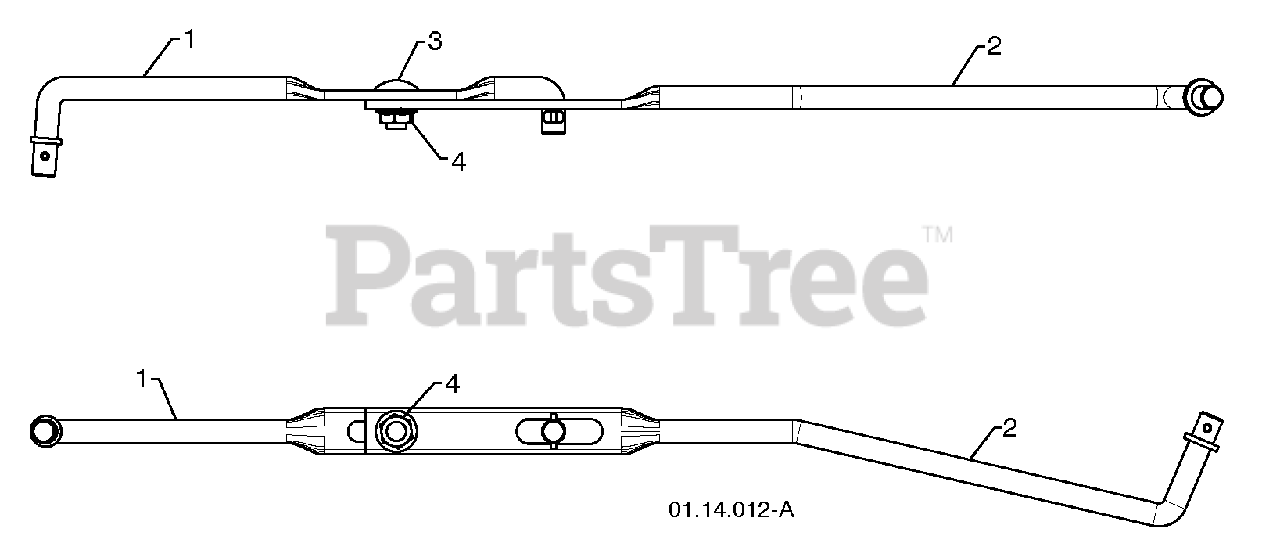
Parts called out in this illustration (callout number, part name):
1	SHIFTER ROD TOP
2	SHIFTER ROD BOTTOM
3	CARRIAGE BOLT 5/16-18 X .75
4	NUT 5/16-18
